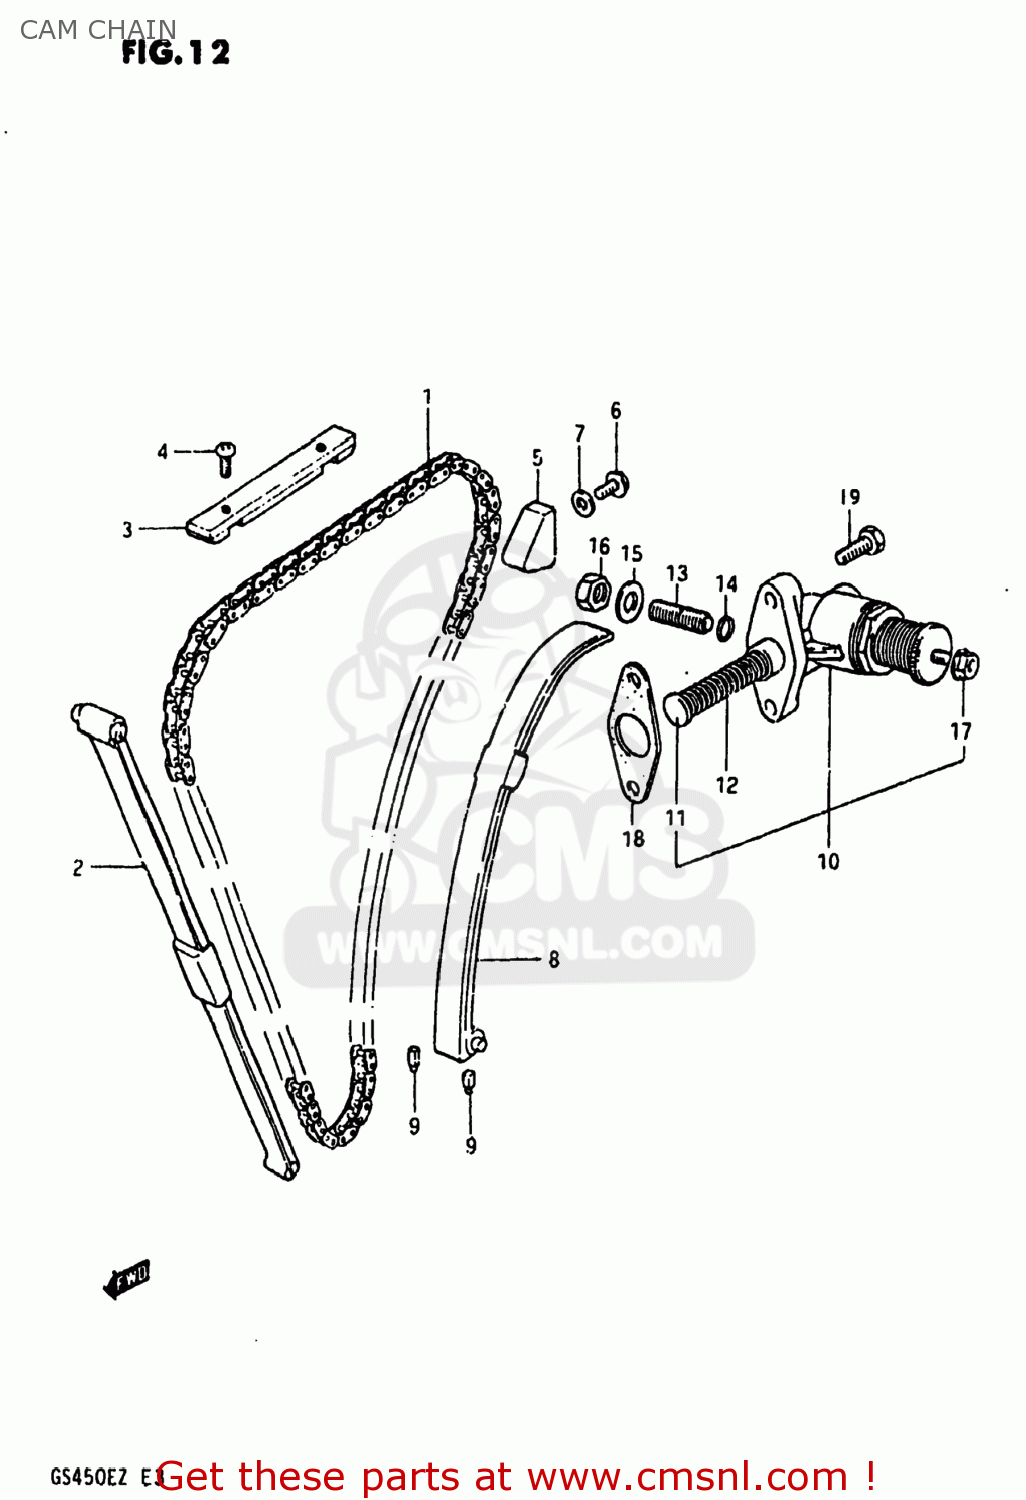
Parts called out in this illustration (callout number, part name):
1	CHAIN,CAMSHAFT DRIVE(120L)
2	GUIDE,CAM CHAIN NO.1
3	GUIDE,CAM CHAIN NO.3
4	SCREW
5	GUIDE,CAM CHAIN
6	BOLT
7	GASKET (NAS)
8	TENSIONER,CAM CHAIN
9	CUSHION,CAM CHAIN TENSIONER
10	ADJUSTER ASSEMBLY,TENSIONER
11	ROD,PUSH
12	SPRING
13	SCREW
14	O-RING
15	WASHER
16	NUT
17	NUT
18	GASKET,TENSIONER ADJUSTER (MCA)
19	SCREW (6X25)
